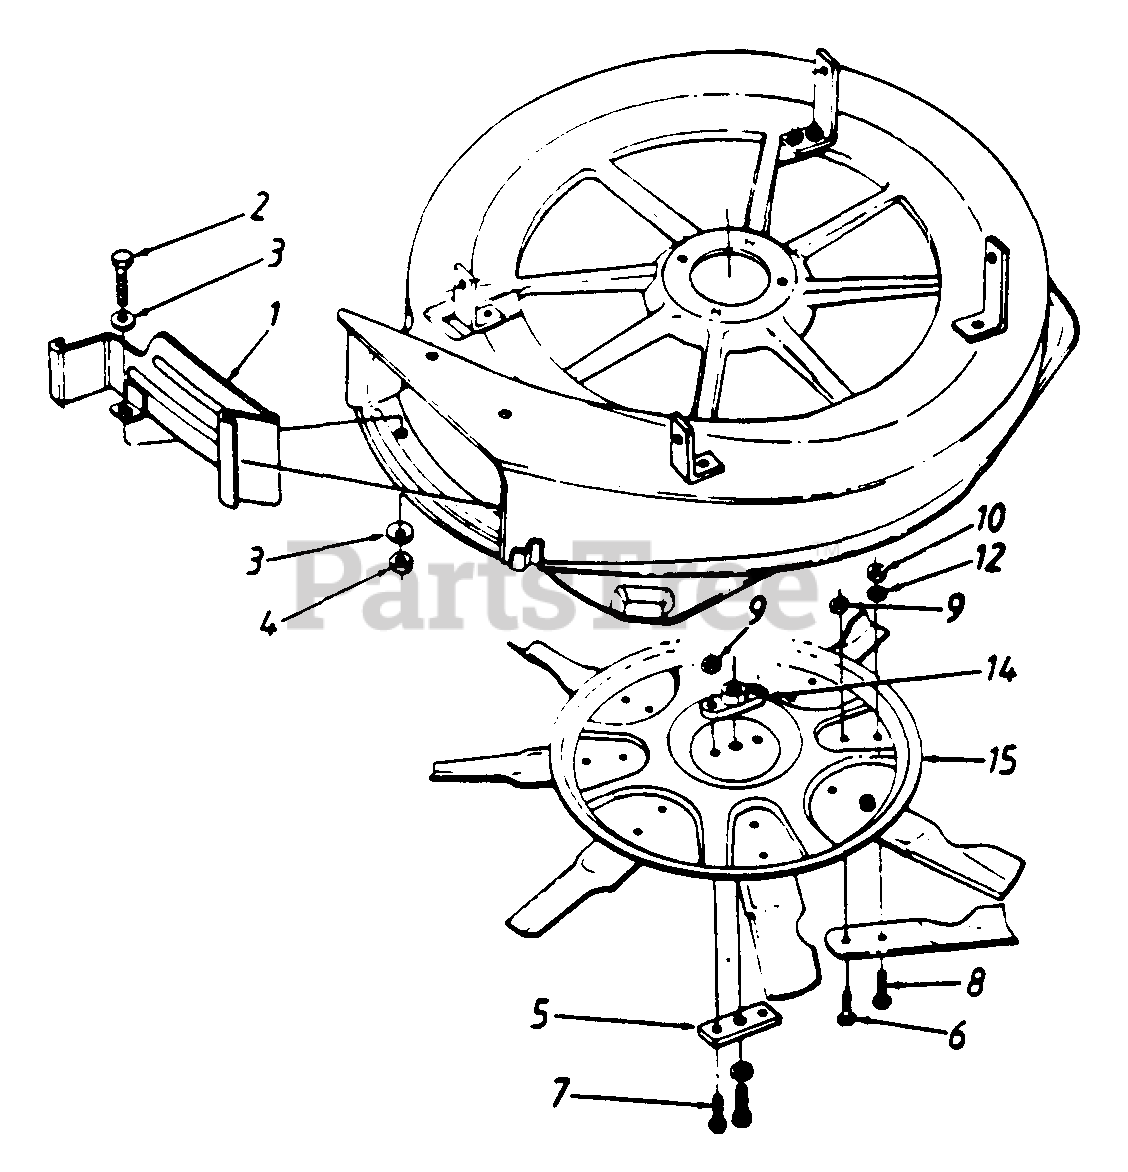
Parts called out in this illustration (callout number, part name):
1	Mulching Baffle Ass'y.
2	Hex Bolt 5/16-18 x .5"
3	Bell-Wash. .325" I.D.
4	Hex L-Nut 5/16-18 Thd.
7	Hex Bolt 5/16-24 x 1.25" Lg. (Gr. 5)
8	Hex Bolt 3/8-24 x .88" Lg.
9	Hex L-Nut 5/16-24 Thd.
10	Hex L-Nut 3/8-24 Thd. (Gr. 5)
11	Extension Spring 3.2" Lg.
12	Fl-Wash. .406" I.D. x .75"
13	30" Mulching Blade Tip
14	Blade Adapter
15	30" Mulching Blade Disc
